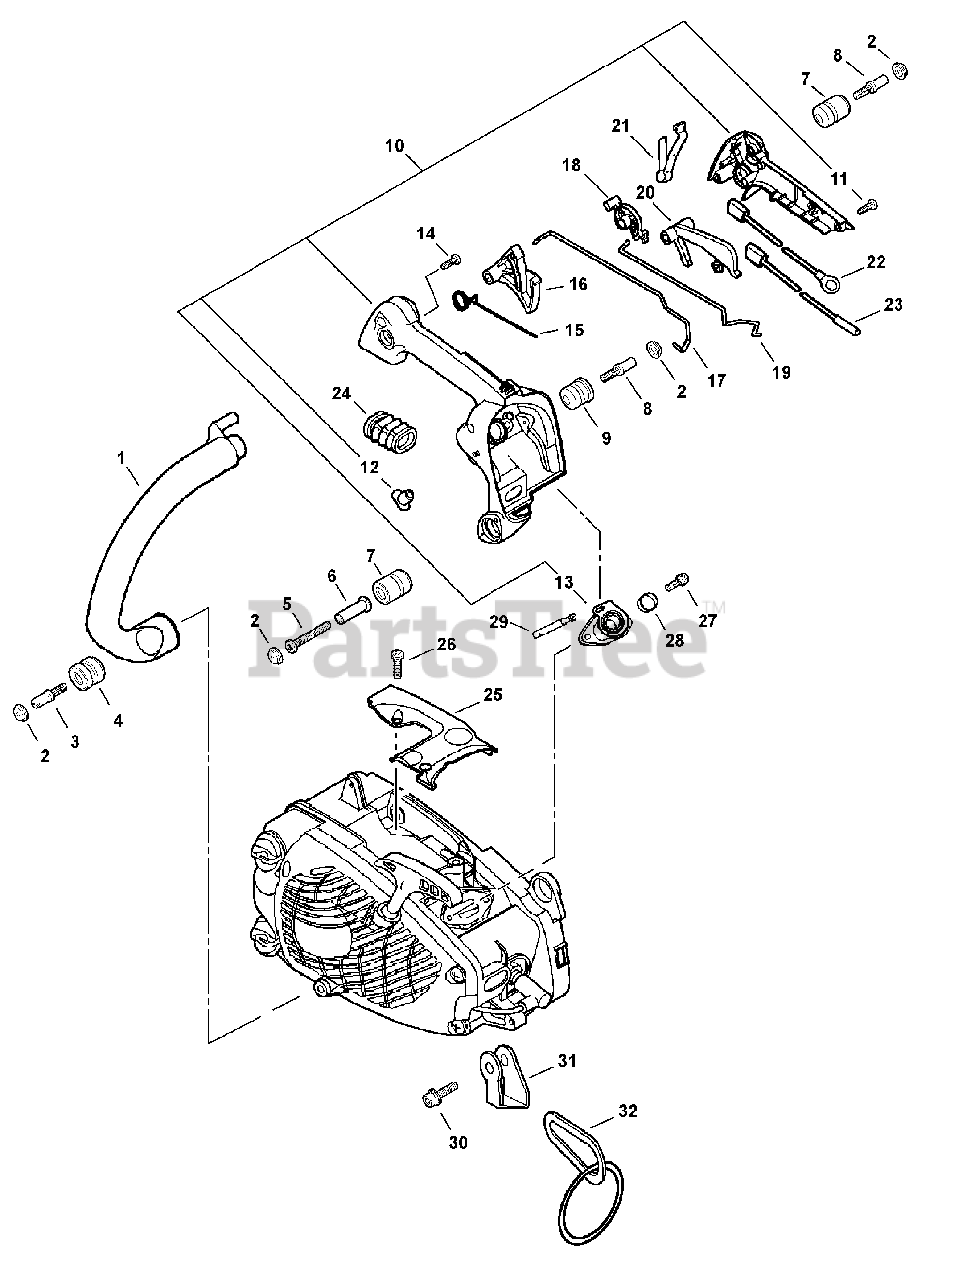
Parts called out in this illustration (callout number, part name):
1	HANDLE - FRONT
2	CAP, CUSHION
5	SCREW - 4X35 -- TAPPING
7	CUSHION
8	STUD, THREADED
10	HANDLE ASSY - REAR
11	SCREW - 4X16
13	BELLOWS, INTAKE
14	SCREW - 5X20 -- TAPPING
15	SPRING, TRIGGER
16	TRIGGER, THROTTLE
17	ROD, THROTTLE
18	LEVER, THROTTLE
19	ROD, CHOKE
20	LEVER, TRIGGER LOCKOUT
21	TERMINAL - GROUND
22	LEAD - GROUND
23	LEAD - IGNITION
24	BELLOWS, INTAKE
25	COVER, DUST
26	SCREW - 4X12 -- TAPPING
27	SCREW - 5X12
28	COLLAR - 16
29	PIPE
30	SCREW - 4X25
31	BRACKET, STRAP
32	HANGER KIT
